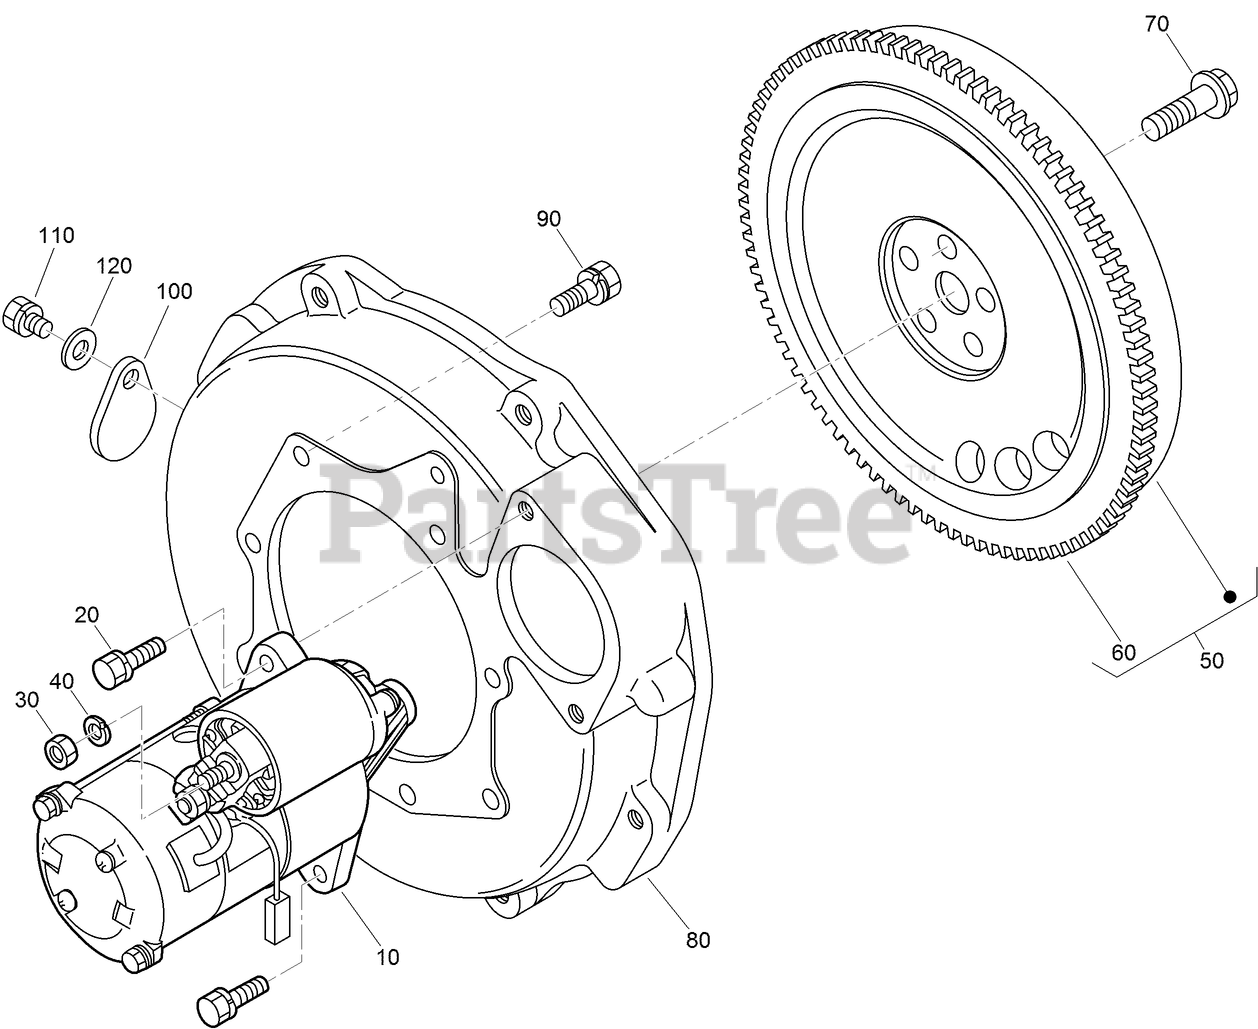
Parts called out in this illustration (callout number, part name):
10	STARTER ASM
40	WASHER-SPRING
50	FLYWHEEL ASM
60	GEAR-RING
70	BOLT-FLYWHEEL
80	HOUSING-FLYWHEEL
120	WASHER-PLAIN
